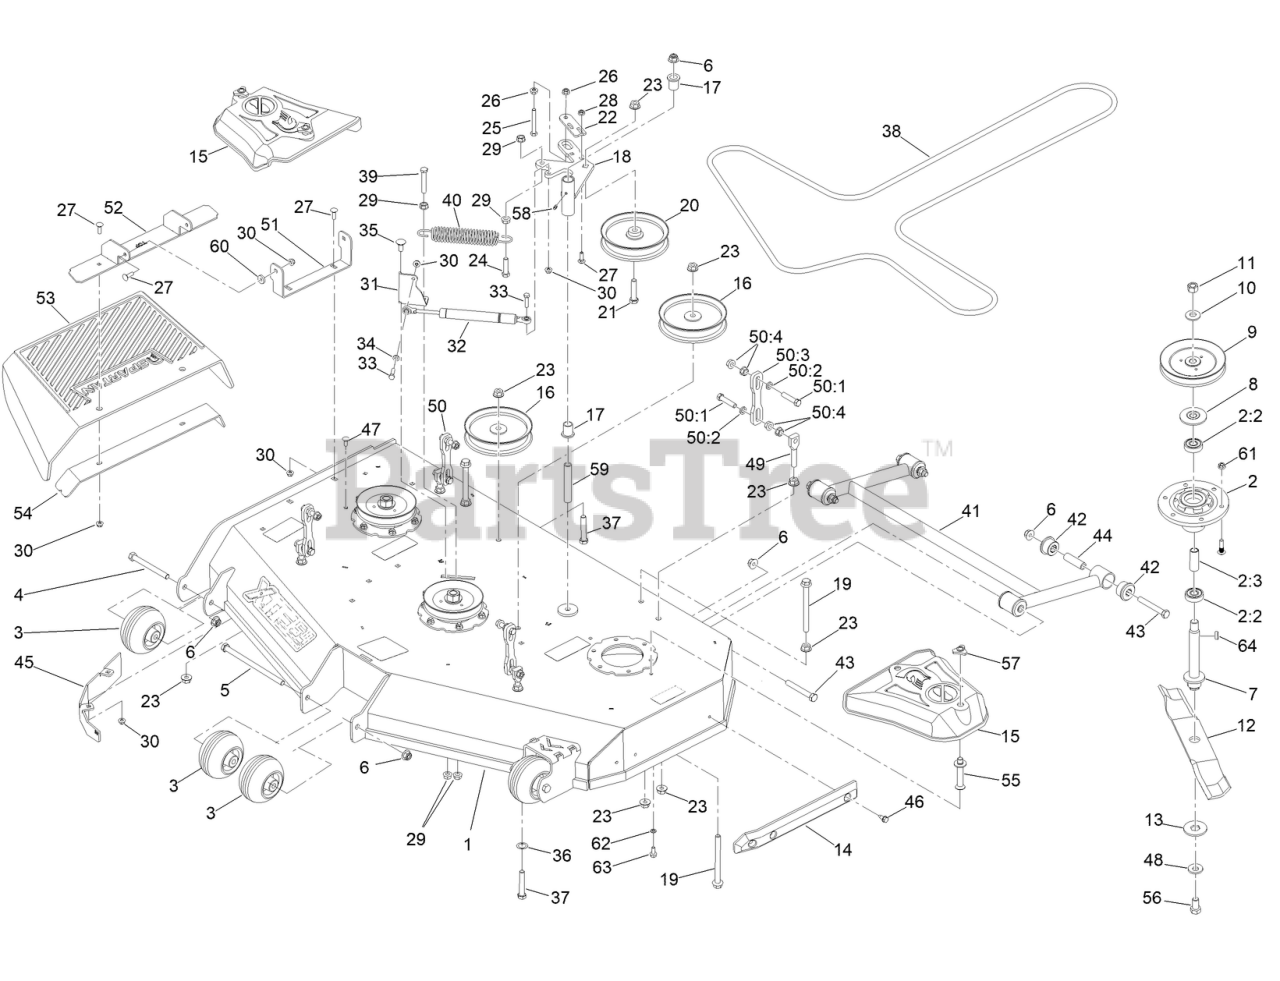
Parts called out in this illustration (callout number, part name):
1	ASM-DECK W/DECALS
2	SPINDLE ASM 6" DECK
2:2	BEARING-BALL
2:3	SPACER, BEARING
3	MWR ANTI-SCALP WHL W/O GREASE FITTING
4	SCREW-HH
5	1/2-13 X 8-1/2 HEX C/S GR 2 ZINC YELLOW
6	NUT-LOCK
7	SHAFT - SPINDLE
8	GUARD,BEARING TOP .989
9	PULLEY
10	M20 SPRING WASHER (44.5MMOD/ 3.3MM THK)
11	M20X1.5 C8.8 HEX NUT
12	BLADE-ROTARY
13	WASHER-HEX
14	MWR NYLON DECK GUARD
15	COVER BELT
16	6-3/4IN IDLER PULLEY 15/16IN SPACER ASSY
17	3/4IN ID X15/16IN OD X 1-1/8IN FLNG BUSH
18	MWR DECK IDLER PULLEY ARM ASSY PAINT
19	1/2-13 X 5-1/2 HEX FLANGE BOLT GR 8 ZY
20	6-3/4IN IDLER PULLEY 7/16IN SPACER ASM
21	1/2-13 X 2-1/4 HEX C/S GR 5 ZINC
22	DECK IDLER PULLEY BELT RETNR BRKT PAINT
23	NUT-HHF
24	SCREW-HH
25	SCREW-HH
26	3/8-16 HEX FLANGE NUT W/SERR ZINC YELLOW
27	5/16-18 X 1 CARRIAGE BOLT GR 8 YZ
29	NUT-HF
30	NUT-HF, NI
31	DECK BELT IDLER DAMPER MTG BRKT PAINTED
32	IDLER GAS SPRING
33	SCREW-HH
34	.312IDX.625ODX.062 THK THRUST BRG OI BRZ
35	SCREW-CARR
36	.767IDX1.125ODX.016 THK TRIP WV WASHER
37	1/2-13 X 2-3/4 HEX FLANGE BOLT (GR.8) YZ
38	54 DECK BELT
40	MWR DECK SPRING
41	54IN/61IN DECK FRAME STABILIZER PAINTED
42	RED A80 SUSP BUSHING
43	1/2-13 X 3-3/4 HEX C/S (GR.5) ZC/YEL
44	UTV A-ARM BUSHING SLEEVE
45	BAFFLE-WIPER 54 PAINTED
46	SCREW-HWH, THREAD CUT
47	BOLT-CARR
48	M16 SPRING WASHER (39MMOD/ 3.9MM THK)
49	MWR DECK HEIGHT ADJUSTMENT STUD
50	MWR DECK SUSP LINK ASSY
50:1	MWR DECK SUSP LINK PAINT
50:2	SCREW-HH
50:3	.443 ID X .749 OD X .125 THK NYLON BLACK
50:4	NUT-HF
51	MWR CHUTE MTG BRKT PAINTED
52	RT/SRT DECK CHUTE HINGE ASSY PAINT
53	2020 RT/SRT RUBBER DISCHARGE CHUTE
54	2020 DECK CHUTE HINGE BACKER BRKT PAINT
55	PIN-BELT COVER
56	M16X1.5-30MM C10.9 HEX BOLT
57	NUT-KNOB
58	1/4IN DRIVE TYPE GREASE FITTING YZ
59	MWR INNER IDLER SPACER
60	.312 ID X .875OD X .1875 THK F/W NYL
62	WASHER-LOCK
63	SCREW-HHF
64	6MM X 6MM X 20MM ROUNDED MACHINE KEY
